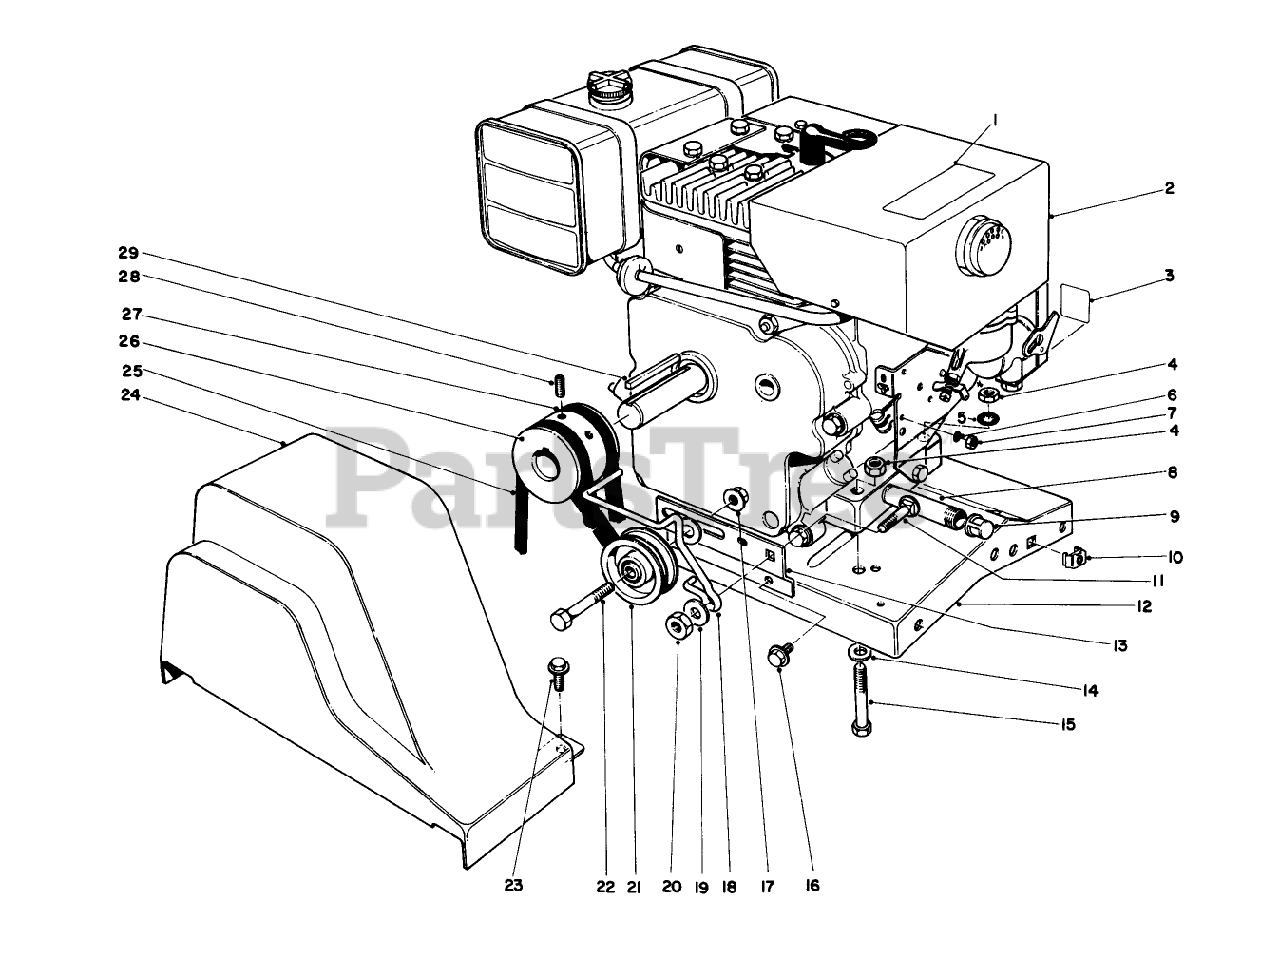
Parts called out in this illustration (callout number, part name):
2	Engine
4	NUT-LOCK, NI
5	WASHER-LOCK, INTERNAL
6	WASHER-LOCK/INT
7	NUT-LOCK
8	NIPPLE-PIPE
9	CAP-PIPE
11	SCREW-CARR
14	WASHER-PLAIN
15	SCREW-HH
16	SCREW-HHFTF
17	NUT-HHF, WHIZ
19	WASHER-FLAT
22	SCREW-HH
23	SCREW-HWH
25	V-BELT
27	V-BELT
